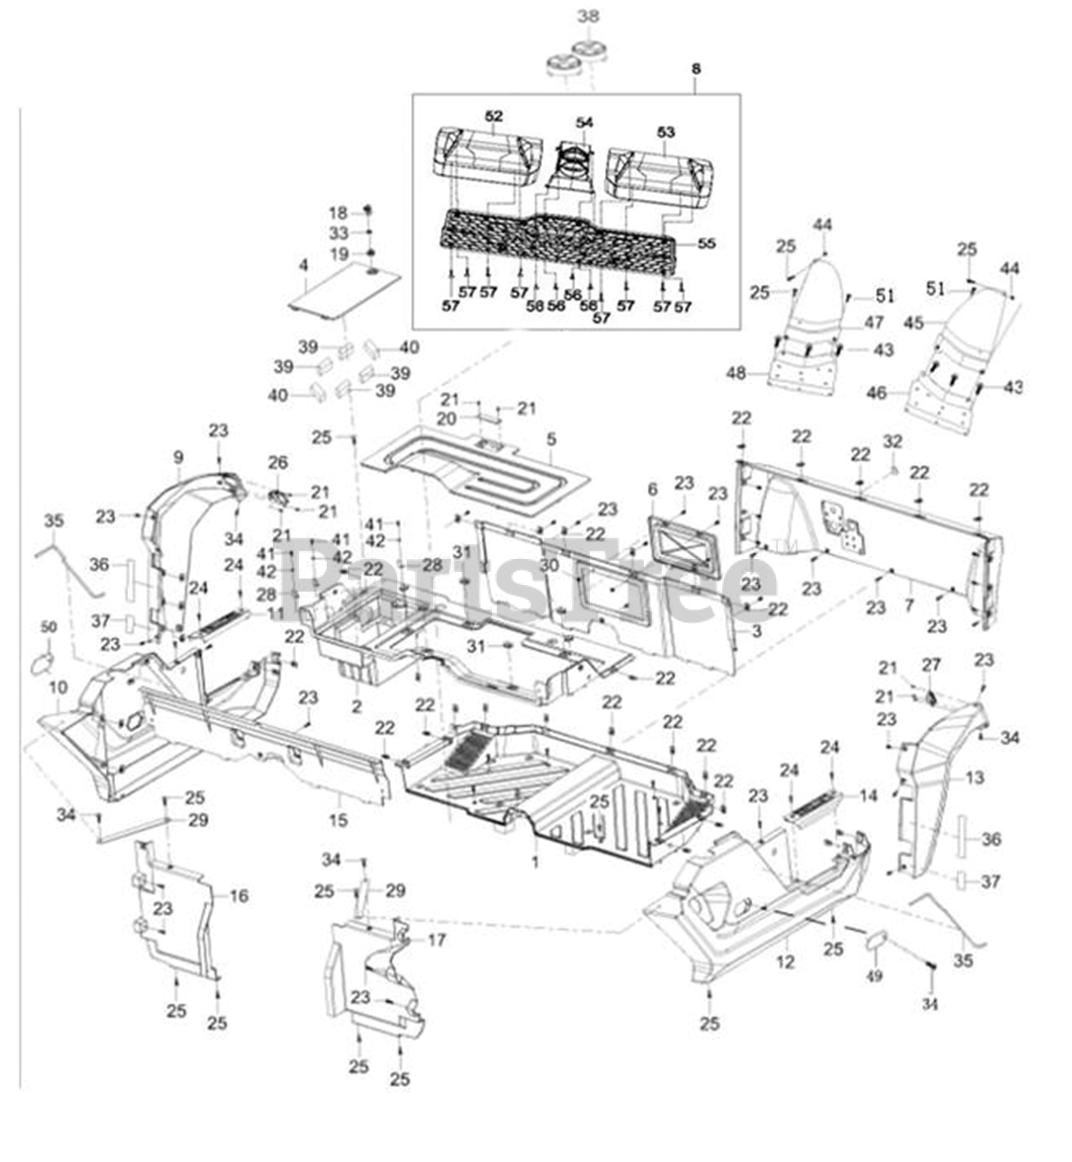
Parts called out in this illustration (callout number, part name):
2	SEAT SUPPORT I
3	SEAT BOX PANEL
4	BATTERY COVER
5	ENGINE COVER
6	COVER - BATTERY BOX
7	FIREWALL PANEL
9	SIDE PANEL - FRONT LEFT
10	SIDE PANEL - MIDDLE LEFT
11	SIDE PROTECTOR - LEFT (BLACK)
12	SIDE PANEL (MID) (RH)
13	SIDE PANEL - FRONT RIGHT (SILVER)
14	SIDE PROTECTOR - RIGHT (BLACK)
15	SEATING PROTECTOR
16	REAR MUDGUARD II
17	REAR FENDER
18	LOCK - BATTERY BOX COVER
19	RUBBER BATTERY COVER GROMMET
20	LOCK - ENGINE COVER
21	SCREW - CROSS HEAD SELF TAPPING
22	CLAMP NUT M6X6
23	SOCKET HEX FLAT HEAD BOLT M6X16
24	HEX HEAD FLANGE BOLT M6X20
25	SCREW M6X16
26	TURN LIGHT - FRONT LEFT
27	TURN LIGHT - FRONT RIGHT
28	STARTER RELAY BRACKET
29	SIDE PLATE SUPPORT I
30	HEX FLANG NUT M6
31	RUBBER WASHER
32	BRAKE PEDAL DUST PAD
33	FLAT WASHER 15x22x1
34	HEX HEAD CAP SCREW M6X16
35	DOOR SEAL 1
36	DOOR SEAL 2
37	DOOR SEAL 3
38	CUP HOLDER
39	BATTERY PAD 90x50x15
40	BATTERY PAD 90x50x15
41	CROSS RECESSED BOLT & WASHER ASM
42	PLAIN FLAT WASHER
43	HEXAGON FLANGE BOLT M6X16
44	LOCK NUT M6
45	FENDER GUARD BRACKET (LOWER RH)
46	FENDER GUARD BRACKET (UPPER RH)
47	FENDER GUARD BRACKET (UPPER LH)
48	FENDER GUARD BRACKET (LOWER LH)
49	ROCK SLIDER MOUNT COVER (RH)
50	ROCK SLIDER MOUNT COVER (LH)
51	SCREW M6X12
52	SEAT BASE PAD (RH)
53	SEAT BASE PAD (LH)
54	CENTER CONSOLE
55	BENCH SEAT BASE PAN
56	SCREW M6X12
57	SCREW M6X20 LG PLT HD
